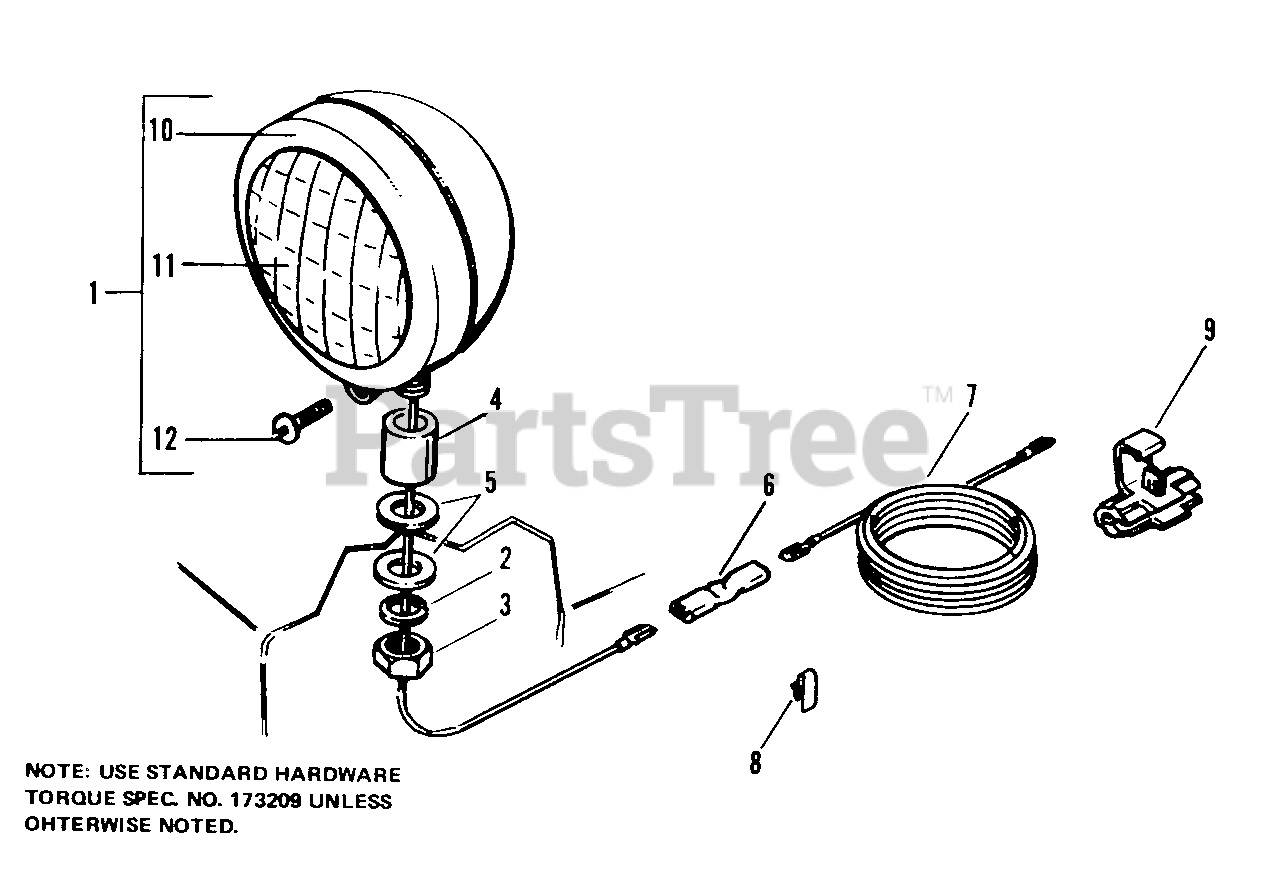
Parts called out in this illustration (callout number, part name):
1	LAMP ASSY
2	LOCKWASHER, 1/2
3	NUT, Hex, Full, 1/2-13
5	WASHER, Plain, 7/16
6	CONNECTOR
8	CLIP, Wire
10	MOULDING ASSY
11	SEAL, Beam
12	SCREW, Moulding
